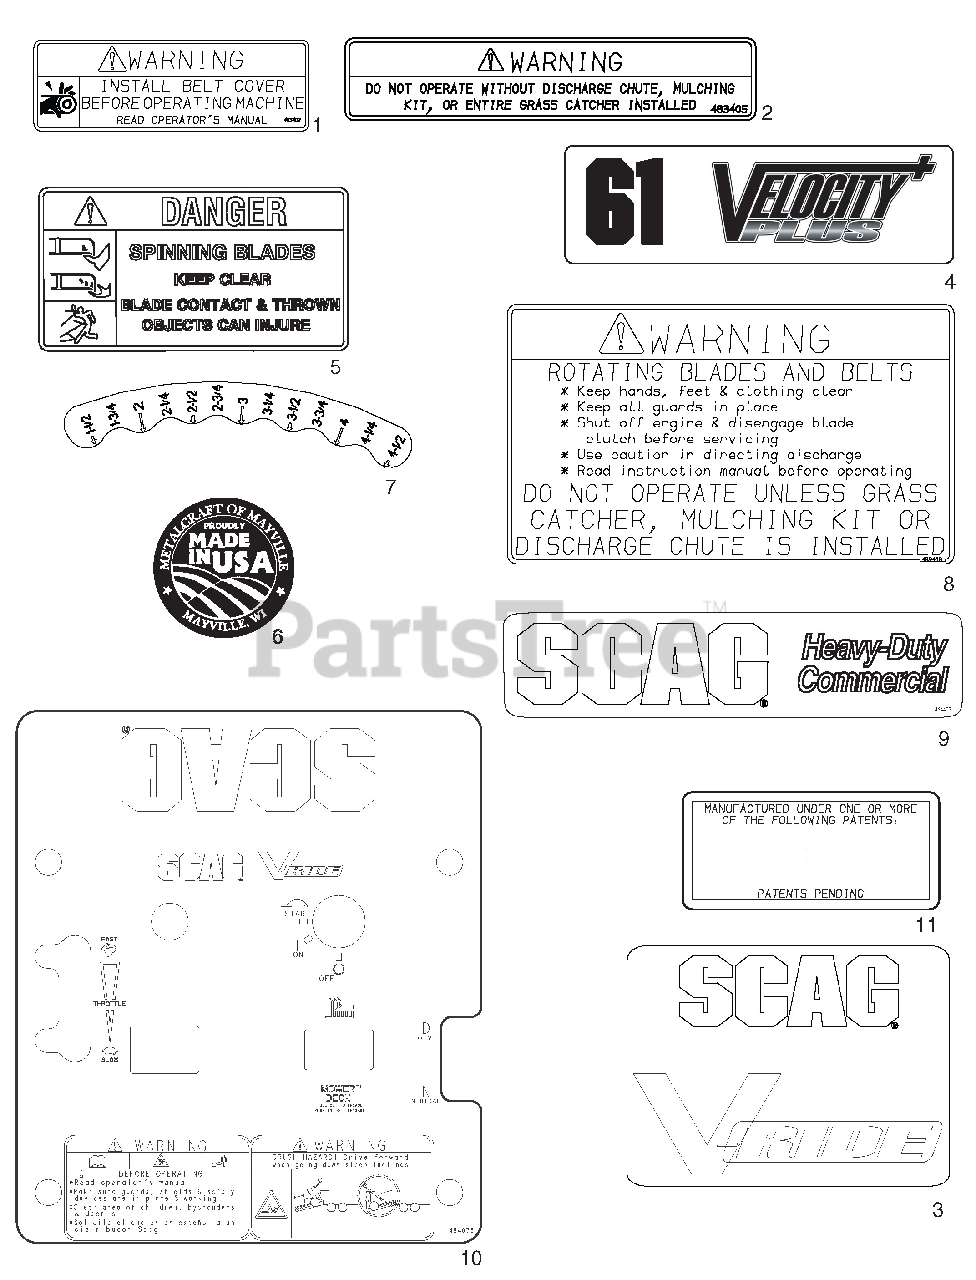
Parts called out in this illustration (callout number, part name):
1	Decal, Warning - Belt Cover
2	Decal, Warning
3	Decal, Belt Cover
4	Decal, 36A
4	Decal, 48V
4	Decal, 52V
4	Decal, 61V
5	Decal, Spinning Blades
6	Decal, Metalcraft - Made in USA
7	Decal, Height-of-Cut
8	Decal, Warning - Knives
9	Decal, Scag Heavy Duty Commercial
10	Decal, Instrument Panel
11	Decal, Patents
